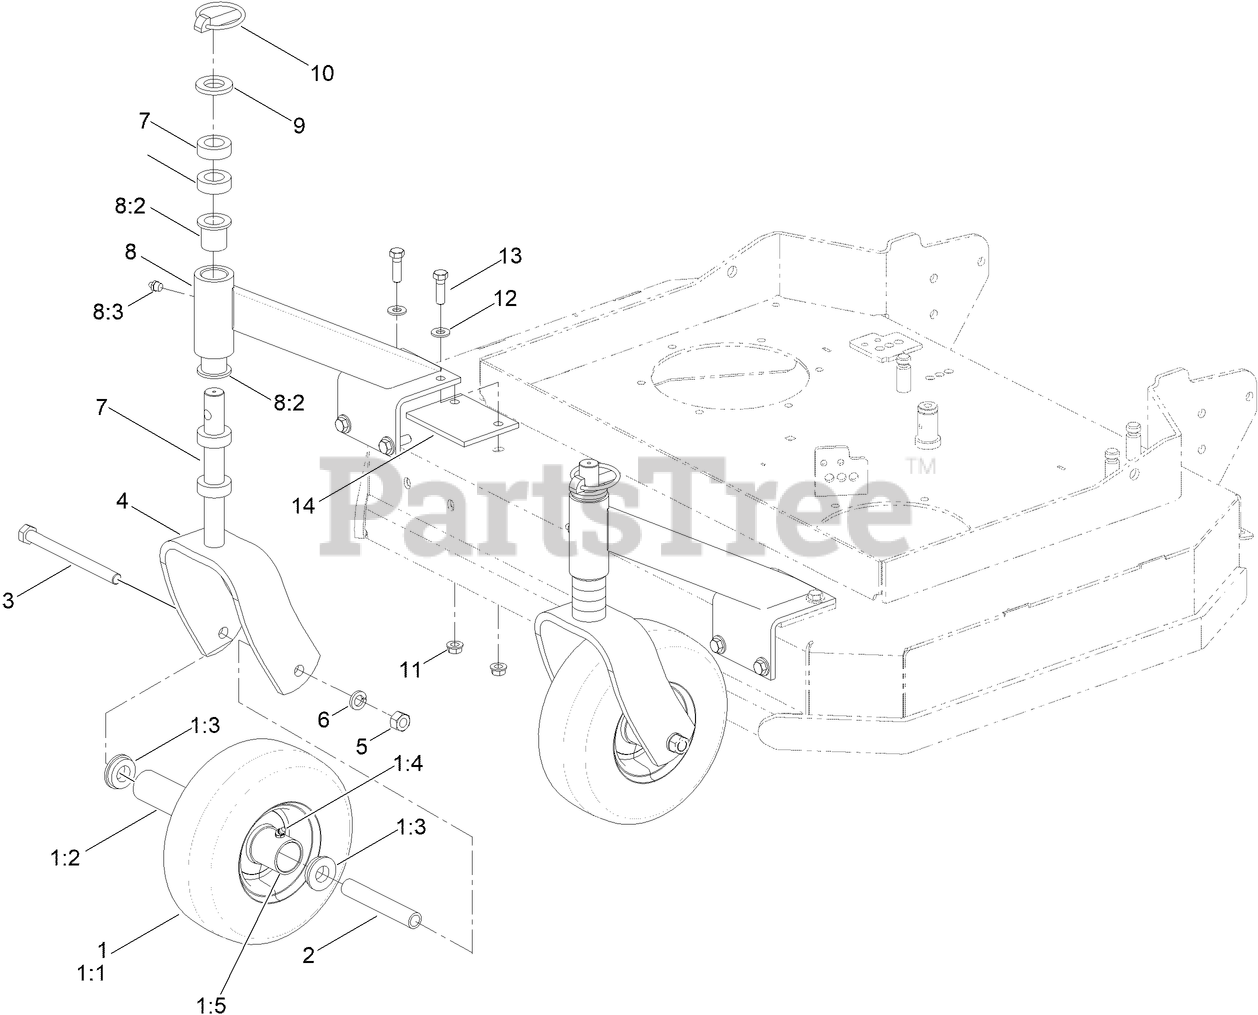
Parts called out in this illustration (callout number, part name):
1	WHEEL AND TIRE ASM
1:1	TIRE
1:2	BEARING
1:3	BUSHING
1:4	FITTING-GREASE
1:5	WHEEL
2	SPACER
3	SCREW-HH
4	FORK-CASTER
5	NUT-HH
6	WASHER-LOCK
7	SPACER-CASTER
8	SUPPORT ASM
8:2	BEARING-FLANGED
8:3	FITTING-GREASE
9	WASHER-FLAT
11	NUT-HHF, WHIZ
12	WASHER-PLAIN
13	SCREW-HH
14	SPACER-CASTER
